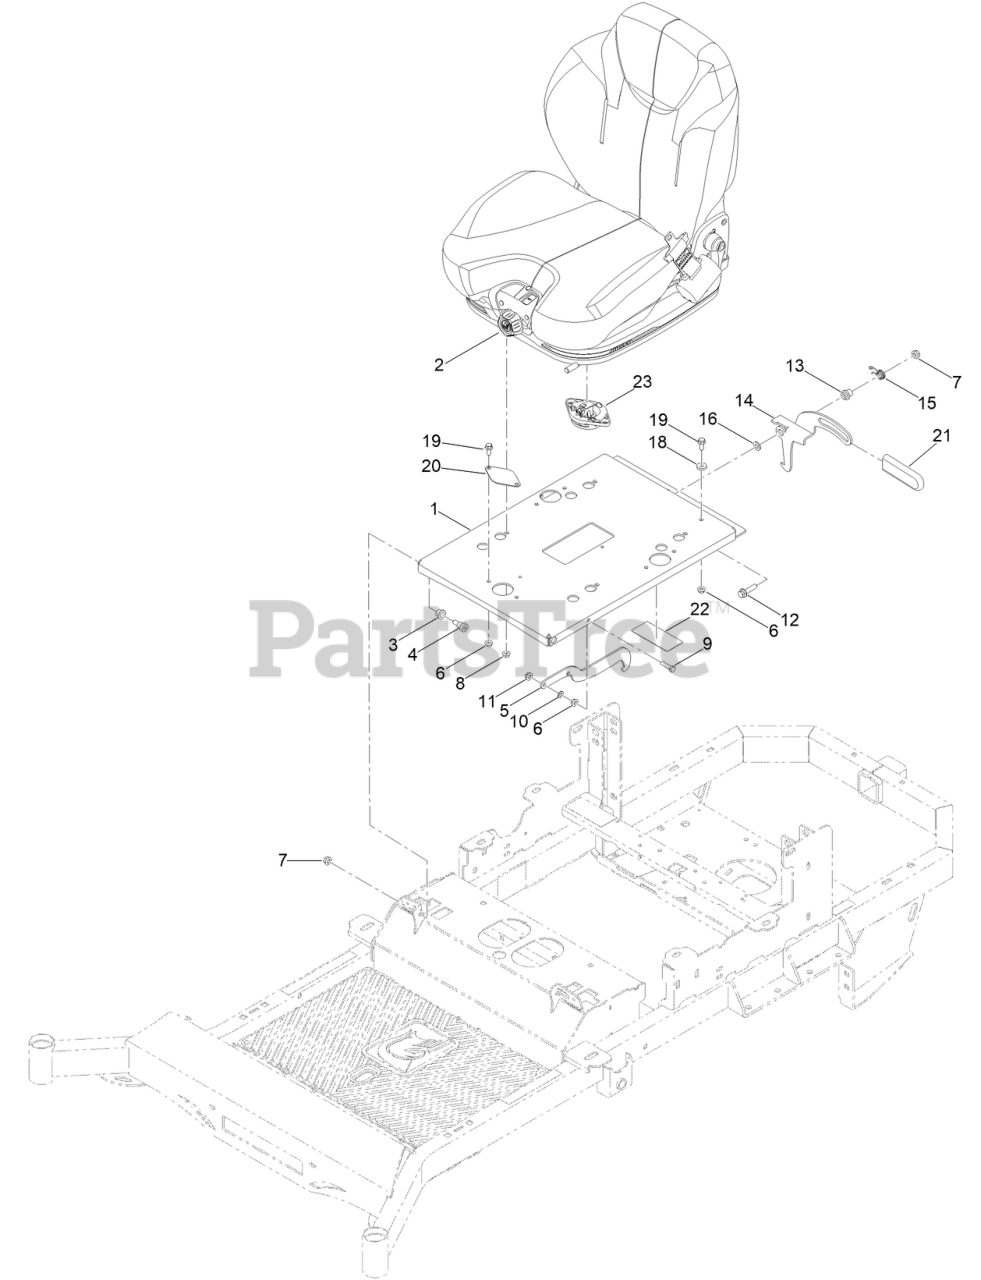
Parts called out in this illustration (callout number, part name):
1	NON 360 SEAT BASE PLATE SAFTY DECAL ASM-
2	KGZ-XD FULL SUSP SEAT
3	1/2IN ID X 5/8IN OD X 1/2IN FLANGE BUSH
4	1/2 X 1/2 SOCKET SHOULDER BOLT ZC YELLOW
5	MWR SEAT LATCH HOOK BLACK
8	5/16-18 NYLON INSERT FLANGE L/NUT ZC
9	SCREW-HH
10	.312IDX.625ODX.062 THK THRUST BRG OI BRZ
11	NUT-HF, NI
12	SCREW-HHF
13	BUSHING-LATCH, SEAT
14	BRACKET-LATCH
15	SPRING-TORSION, LATCH
16	WASHER-FLAT
18	.312 ID X .875OD X .1875 THK F/W NYL
19	SCREW-HHF
20	UNIV FLOATING SEAT COVER PLATE BLACK
21	STAND UP MWR BRAKE ARM GRIP
22	DECAL-WARNING, BATTERY
23	MWR SEAT SWITCH
